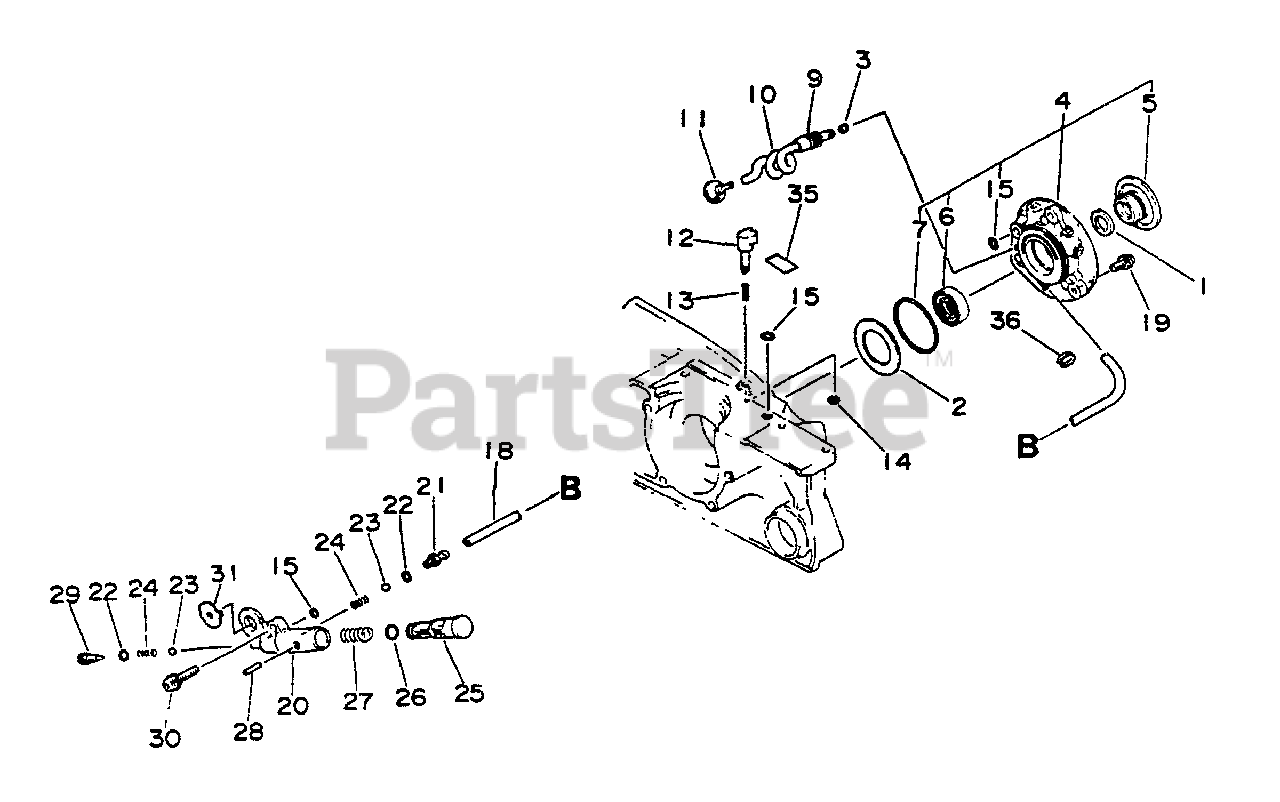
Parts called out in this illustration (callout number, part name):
2	PLATE
3	CLIP 6.6 MM
4	AUTO-OILER ASSY
5	GEAR, WORM
6	SEAL, OIL
7	O-RING
10	PIPE - SPIRAL
11	FILTER, OIL
14	E-RING 3
15	O-RING 3
18	PIPE, OIL
19	SCREW - 4×10
20	BODY, OIL PUMP
21	CONNECTOR, PIPE
23	VALVE, BALL
24	SPRING, VALVE
25	PISTON, OIL PUMP - BLACK
26	O-RING 7 MM
28	PIN, SPRING 2×16
29	ADAPTOR, OIL PUMP
30	SCREW - 5×20
31	BRACKET, OIL PUMP
35	LABEL, CAUTION
36	CLIP 6.6 MM
